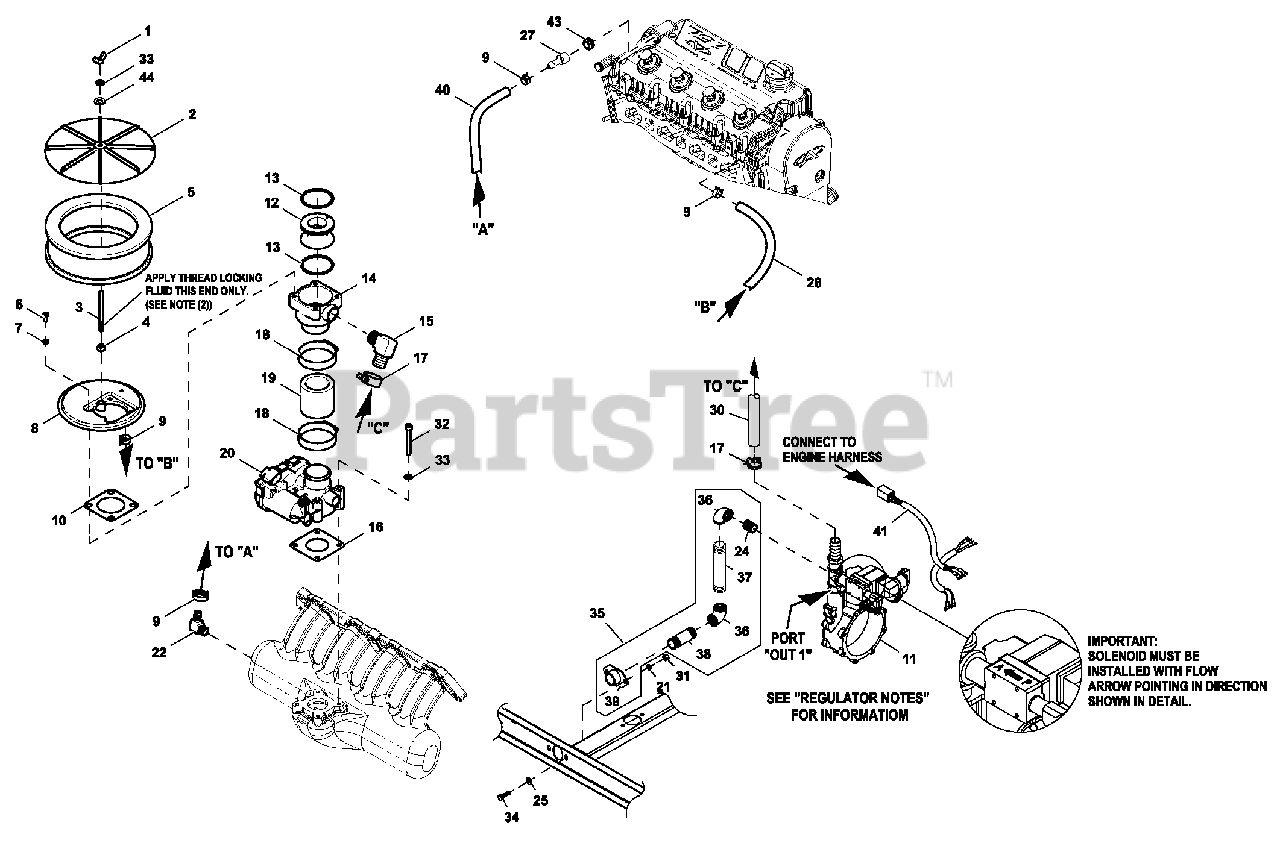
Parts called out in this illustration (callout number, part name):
1	NUT WING 1/4-20
2	COVER AIR CLEANER
3	STUD TH 1/4-20 X 3 G2 ZNC FULL
4	NUT HEX 1/4-20 STEEL
5	FILTER ELEMENT
6	SCREW PPHM M5-0.8 X 12 ZNC
7	WASHER LOCK M5
8	ADAPTER, CARBURETOR W/PVC CONN
9	CLAMP HOSE BAND .63
10	GASKET BOSCH 32 & 40
11	FUEL REG. REWORK 1.5L
12	VENTURI THROTTLE 21 MM
13	O-RING 47.625 ID X 2.38 WIDTH
14	MIXER ACTUATOR 32MM MACHINED
15	BARBED EL 1/2"NPT X 3/4 HOSE
16	GASKET BOSCH 32
17	CLAMP HOSE #10 .56-1.06
18	CLAMP HOSE #28 1.32-2.25
19	HOSE 1.5 ID X 2 LG 20R4
20	ACTUATOR BOSCH 32 GOVERNOR
21	WASHER LOCK M8-5/16
22	BARBED EL 90 1/4NPTX3/8
24	NIPPLE CLOSE 3 /4X 1 .3 75
25	WASHER FLAT 5/16 ZINC
26	HOSE 3/8 ID SINGLE BRAID (20" LG)
27	VALVE, PCV
30	HOSE 3/4 ID SAE-30R2 (16.50"LG)
31	NUT HEX M8-1.25 G8 YEL CHR
32	SCREW SHC M6-1.0 X 50 C8.8
33	WASHER LOCK M6-1/4
34	SCREW HHC M8-1.25 X 20 G8.8
35	ASSY REG INLET NPT FITTINGS
36	ELBOW 90D 3/4 NPT
37	NIPPLE PIPE 3/4NPTX4.5 BLK IRN
38	NIPPLE PIPE 3/4NPT X 2
39	FLANGE FUEL INLET
40	HOSE 3/8 ID SINGLE BRAID (12"LG)
41	HARN FUEL JUMPER SINGLE REG
43	GROMMET PCV VALVE
44	WASHER FLAT 1/4-M6 ZINC
